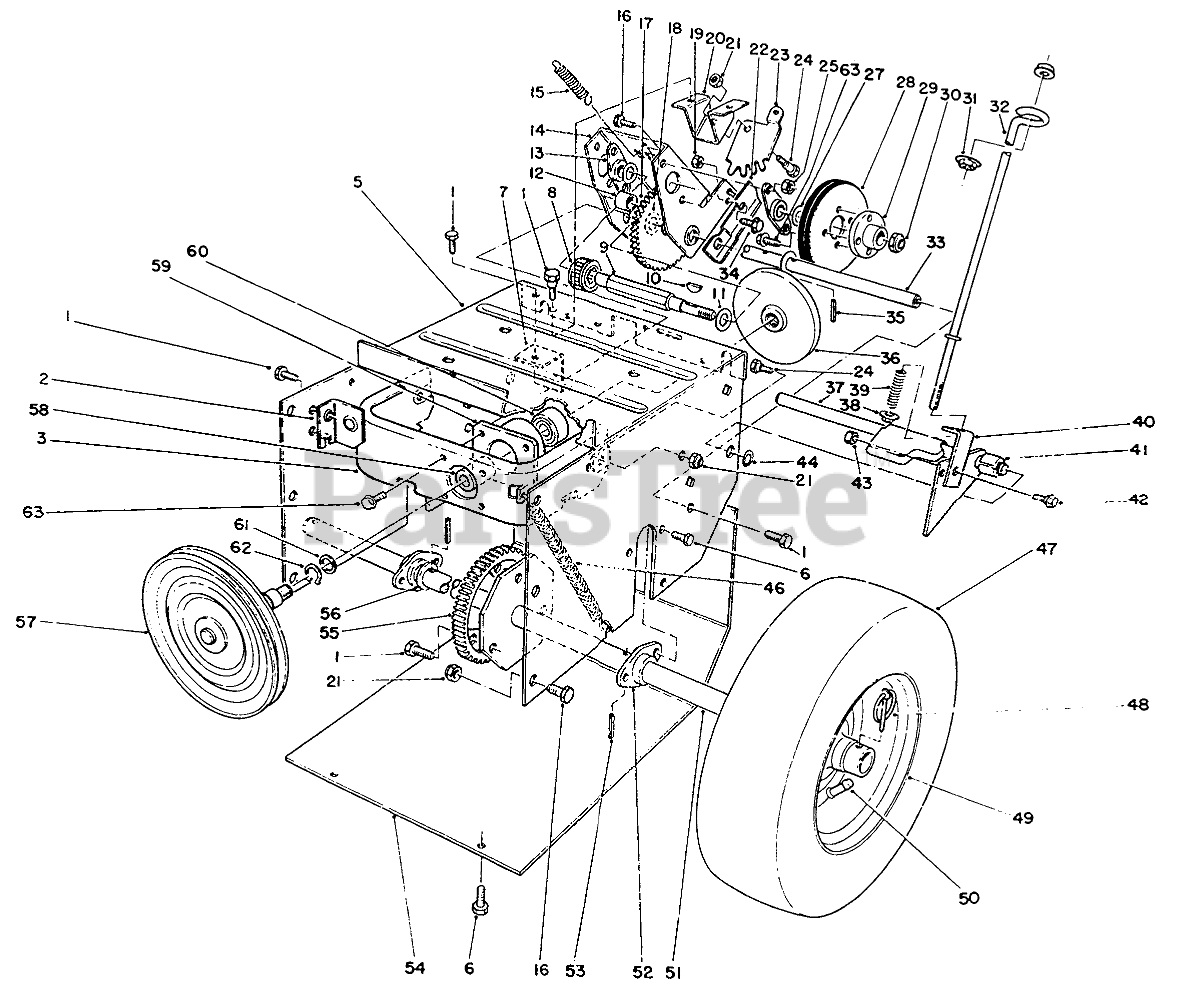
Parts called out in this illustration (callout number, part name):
1	SCREW-HWHTF
2	BRACKET-MOUNT, FRONT
3	Frame-Friction Plate
5	Frame-Traction
6	SCREW-HWH
7	BRACKET-MOUNT, REAR
8	PINION
9	SHAFT-WHEEL, FRICTION
10	KEY-WOODRUFF
11	WASHER-FLAT
12	5/8ID X 1LG BUSHING
13	BEARING-WHEEL, FRICTION
14	BRACKET-SLIDING
15	SPRING-TRACTION
16	SCREW-HH
17	Intermediate Gear & Bushing (Incl. ref. #12)
18	WASHER-SPECIAL
19	NUT-LOCK, NI
20	MOUNT-LEVER
21	NUT-LOCK, NI
22	CAM-RECEIVER
23	GEAR-QUADRANT
24	BOLT-SHOULDER
25	NUT-LOCK, NI
27	WASHER-THRUST
28	WHEEL-FRICTION
29	HUB-WHEEL, FRICTION
30	NUT-LOCK, NI
31	NUT-HF
32	ROD-TRACTION, LOWER
33	SHAFT-PIVOT
34	SCREW-HH
35	PIN-SPRING
36	PLATE-FRICTION
37	Traction Engagement Asm.
38	NUT-HHF
39	SPRING
40	BRACKET-TRACTION
41	SPACER
42	SCREW
43	NUT-LOCK, NI
44	RING-RETAINING
46	SPRING-PLATE, FRICTION
48	PIN-LYNCH
49	RIM-WHEEL
50	TUBE-INNER
51	SHAFT-AXLE
52	BEARING-AXLE
53	PIN-SPRING
54	Bottom Cover
55	GEAR-AXLE
56	WASHER-THRUST
57	PULLEY AND DRIVE ASM
58	BUSHING
59	HUB-FRAME, TRACTION
60	BEARING-BALL
61	WASHER-THRUST
62	RING-RETAINING, EXT
63	SCREW
